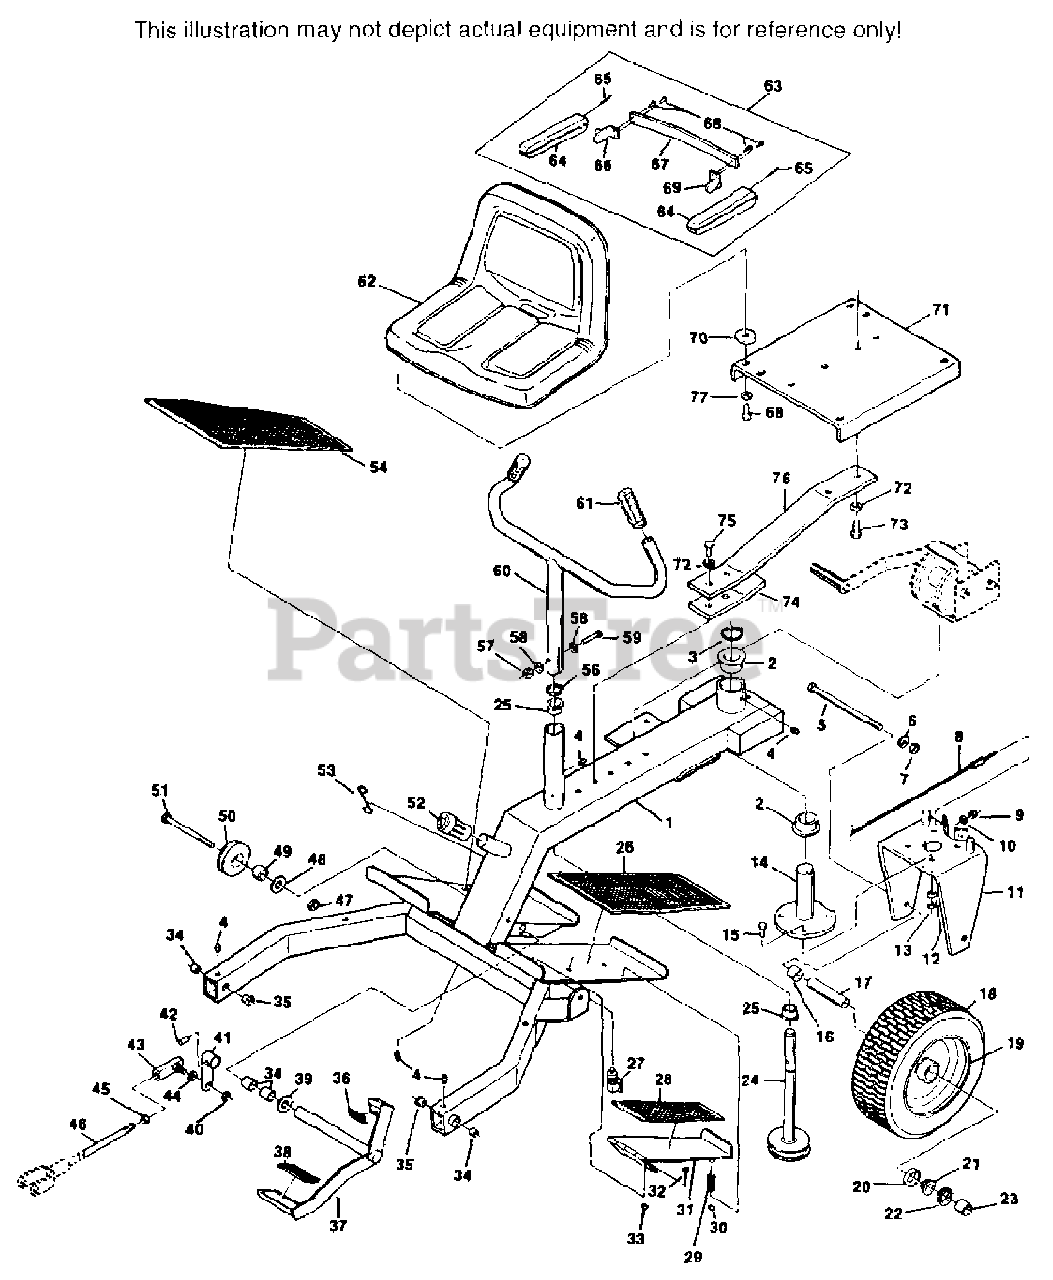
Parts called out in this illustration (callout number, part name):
1	STEERING FRAME(INCL. BUSHINGS & GREASE
2	BRONZE BUSHING
3	RETAINING RING, 1-1/8 EXTERNAL
4	GREASE FITTING
6	LOCK WASHER, 5/8 SPRING
8	CABLE, STEERING
9	HEX NUT, 1/4-28 LOCK
11	REAR WHEEL YOKE
12	LOCK WASHER, 3/8 SPRING
14	REAR WHEEL PIVOT
16	SPACER, REAR WHEEL, LONG
17	SLEEVE, REAR WHEEL
18	REAR WHEEL ASSY.(INCL. 19, 20, 21, 22)
19	RIM ONLY
20	BEARING CUP
21	BEARING CONE
22	SEAL, GREASE
23	SPACER, REAR WHEEL, SHORT
24	STEERING SHAFT
25	BRONZE BUSHING
26	PAD, LH
27	SWITCH, FOOT SAFETY
28	PAD, SAFETY PEDAL
29	SPRING, FOOT SAFETY SWITCH
30	HEX, NUT, ELASTIC STOP LOCK, 1/4-20
31	PEDAL, FOOT SAFETY SWITCH
34	BRONZE BUSHING
35	BRONZE BUSHING
36	PAD, FOOT PEDAL, REVERSE
37	FOOT PEDAL
38	PAD, FOOT PEDAL, FORWARD
41	FOOT PEDAL ARM
42	PIN, DRIVE LOCK, 3/16 X 1-1/4
43	BALL JOINT
46	CONTROL ROD
47	HEX NUT, ELASTIC STOP NUT, 1/2-13
49	BRONZE BUSHING
50	PULLEY, WINCH CABLE
52	BUMPER STOP COVER
54	PAD, RH
56	RETAINING RING, 7/8 EXTERNAL
57	HEX NUT, 5/16-18 CENTER LOCK
58	FLAT WASHER, 11/32 X 11/16 X 16 GA.
60	STEERING HANDLE(INCL. 61)
61	GRIP
62	SEAT ONLY
63	ARM REST KIT(INC. 64,65,66,67,68,69)
64	ARM REST
65	SETSCREW, 3/8-16 X 3/4 FLAT POINT
66	MOUNTING BRACKET, RH
67	BACK STRAP
69	MOUNTING BRACKET, LH
70	FLAT WASHER, 13/32 X 1-1/2 X 7 GA.
71	SEAT PLATE
72	LOCK WASHER, 7/16 SPRING
74	REINFORCEMENT, SEAT SPRING
76	SEAT SPRING
77	LOCK WASHER, 5/16 SPRING
